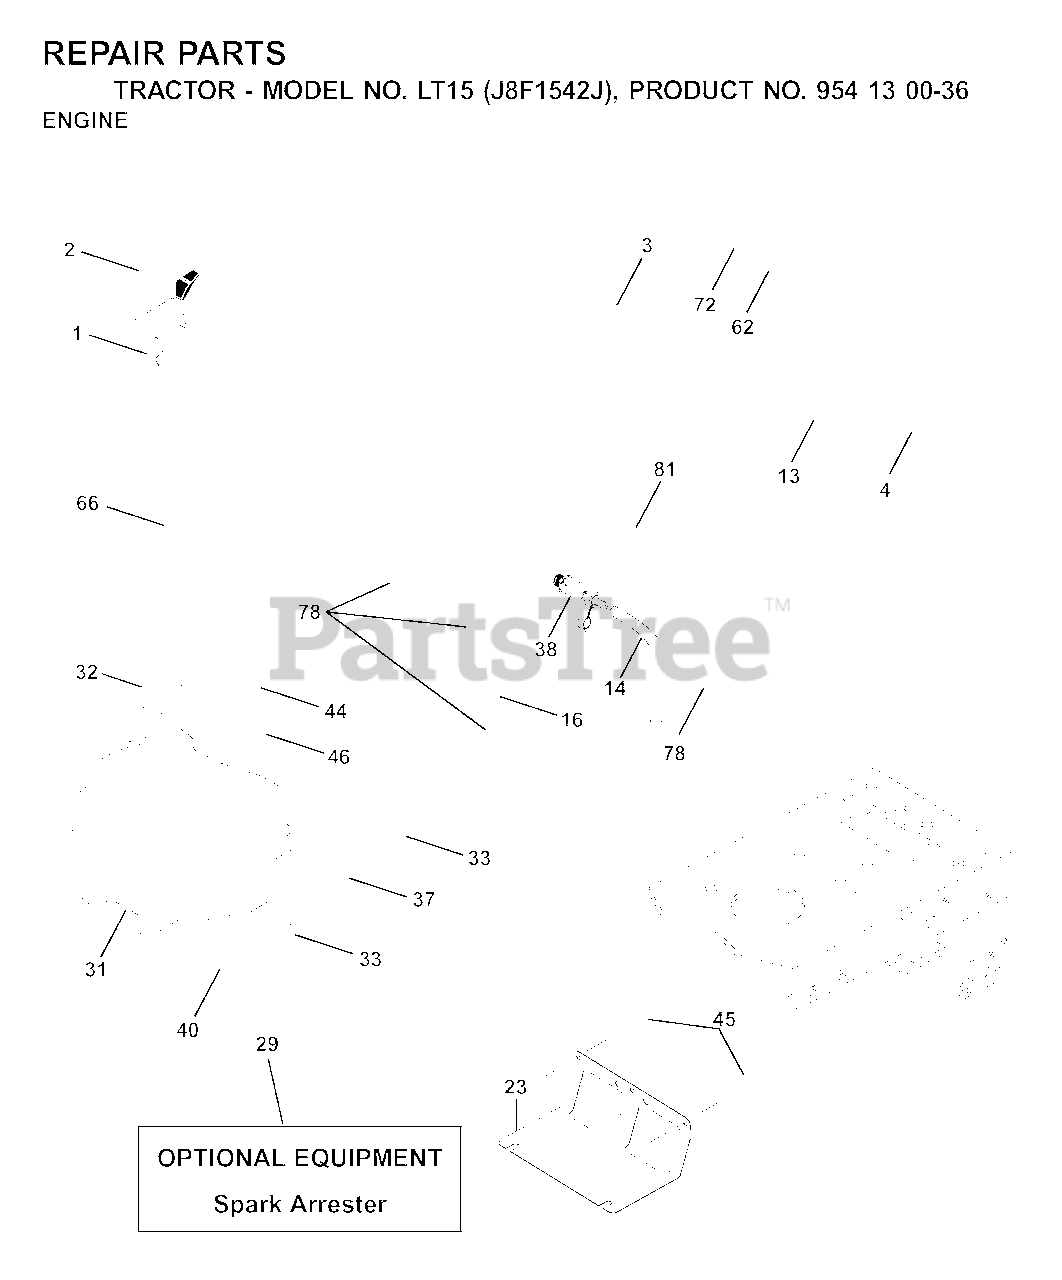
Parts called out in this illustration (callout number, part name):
1	THROTTLE CONTROL CABLE
2	SCREW LT
13	REPL BY 532 27 22-93
14	TUBE, DRAIN OIL ASM.
16	LOCKWASHER
23	SHEILD.BROWNING.DBR.GUARD
29	ARRESTER SPARK (OPTIONAL)
31	TANK, 2GAL
32	FUEL CAP
33	HOSE CLAMP
37	LINE.FUEL.20
38	PLUG, OIL DRAIN EASY
40	GROMMET T
44	SCREW HEXWSHR 1/4-20X3/4
45	SCREW, 3/8-16X3/4
62	LOCKWASHER
66	STOP THROTTLE
72	SCREW
78	SCREW.3/8-16
81	NUT
